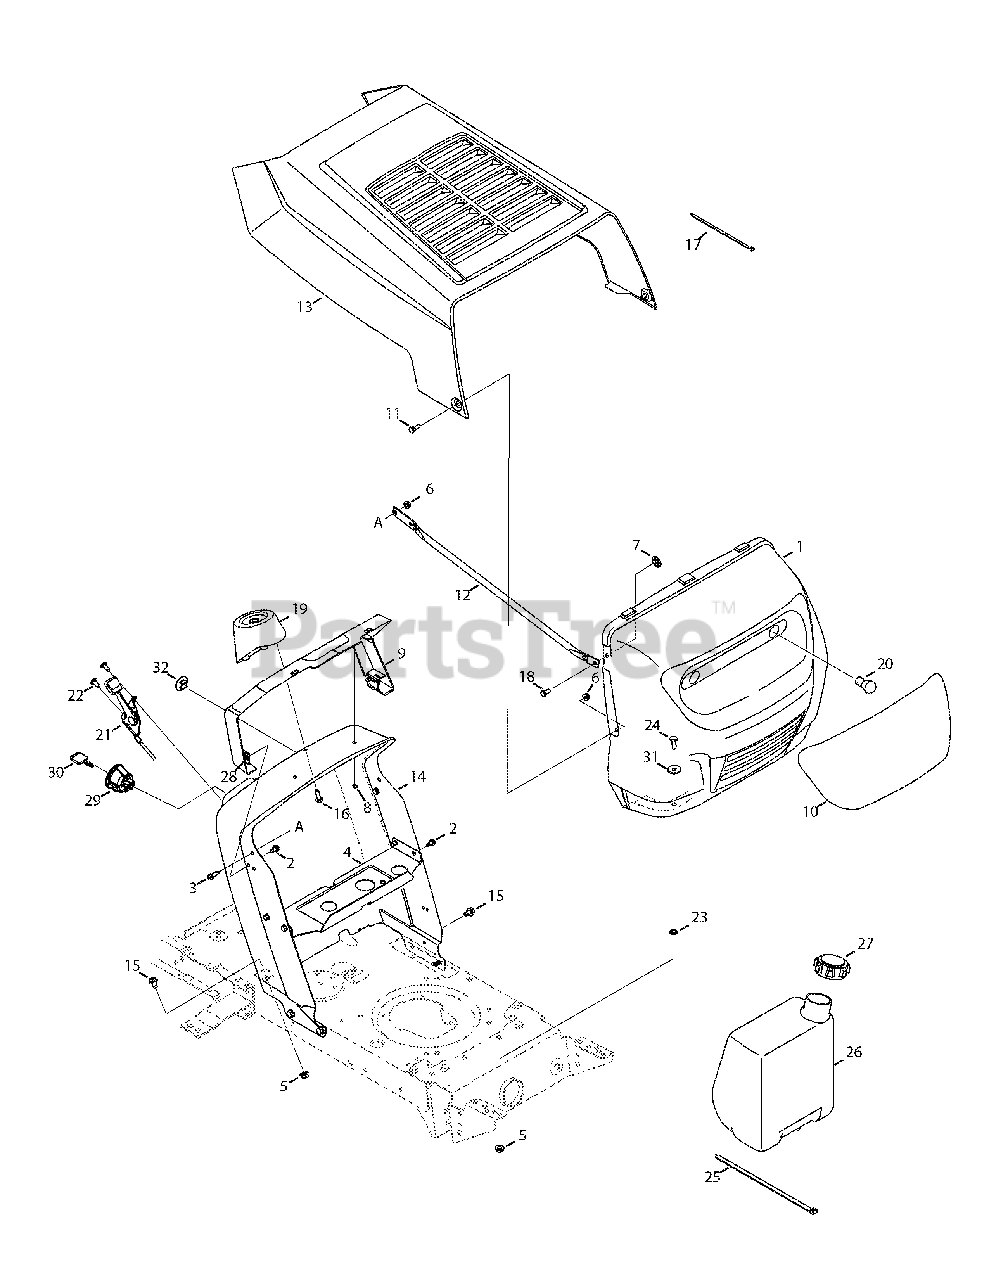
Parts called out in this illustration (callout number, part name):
2	Screw, 1/4-20, 0.500
3	Screw, 1/4-20, 0.750
5	Nut, Flange Lock, 5/16-18, GrF
6	Nut, Flange Lock, 1/4-20, GrF
7	Nut, Push-on, .25 Dia
8	Push Nut, .25ID x .50OD
9	Collar, Dash, 0-Style
11	Screw, Shldr, .375 x .125, 1/4-20
15	Screw, 5/16-18, 0.625
16	Screw, 1/4-15, 0.750
17	Cable Tie
18	Rivet, Flat Head 1/4"
19	Support, Steering
20	Headlamp, 12V
21	Throttle/Choke Cable, 25"
22	Screw, 1/4-14, .500
23	Speed Nut, .3125
24	Screw, 5/16-18, .750
25	Cable Tie, 34.75
26	Fuel Tank, 1.5 gal.
27	Fuel Tank Cap
28	Nut, 1/4-20
29	Igntion, Switch (No RMC) 3 Position
30	Key
31	Flat Washer, .344 x 1.00 x .063
32	Dash Plug
